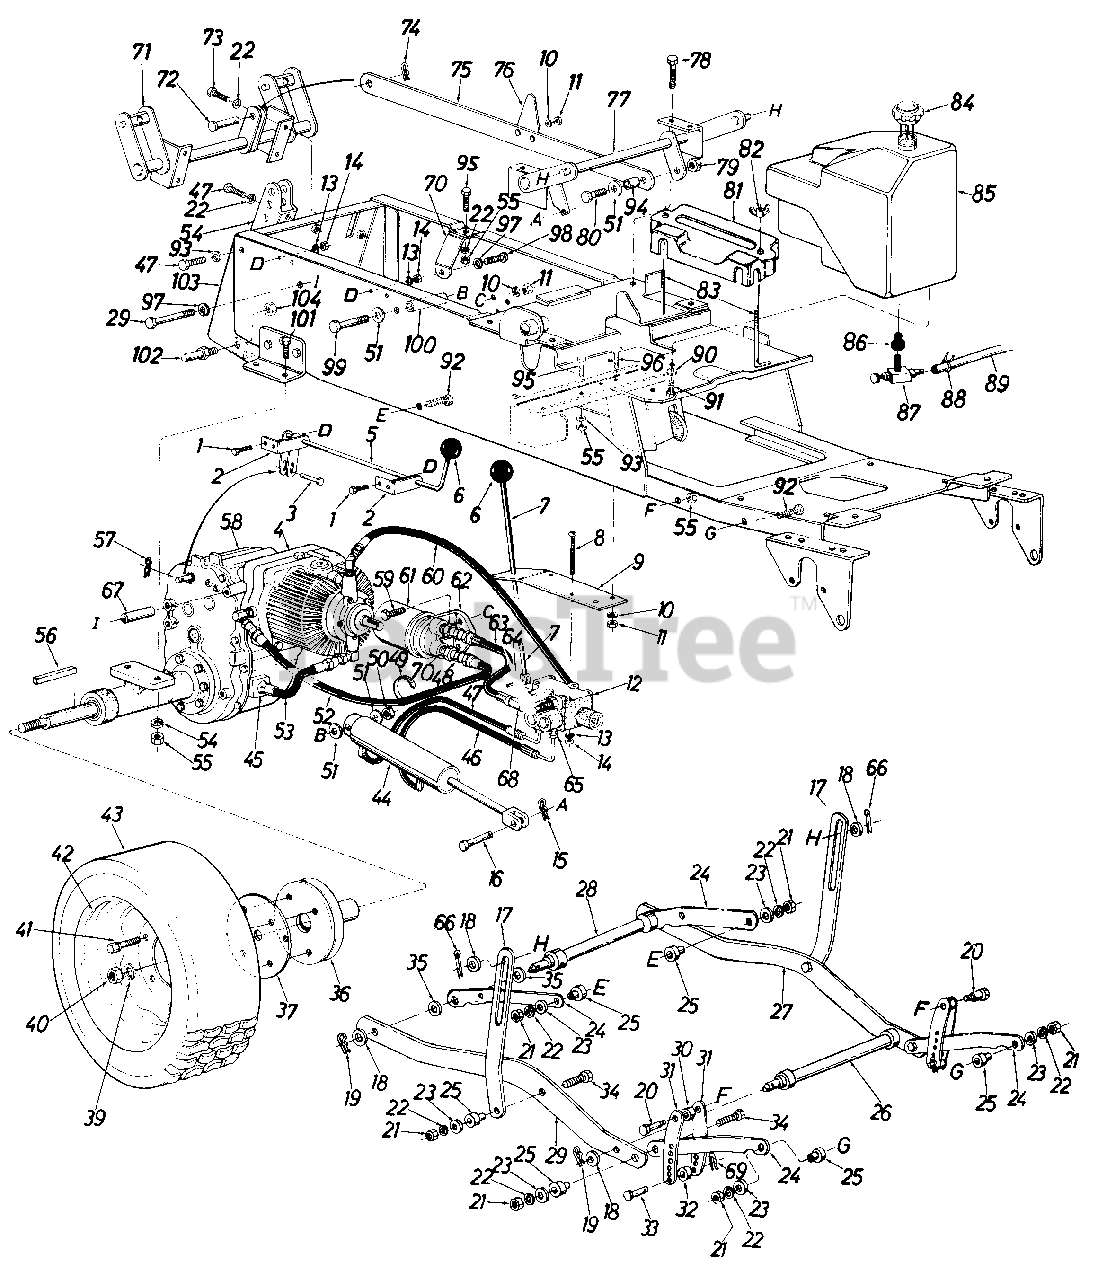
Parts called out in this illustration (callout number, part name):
1	Hex Bolt 1/4-20 x .75" Lg.*
4	Hydrostatic Pump Comp.
5	Hi-Lo Control Handle Ass'y.
6	Ball Knob
7	Cylinder Control Handle Ass'y.
8	Truss Mach. Scr. 1/4-20 x 3.00" Lg.*
11	Hex Nut 5/16-18 Thd.*
12	Valve Ass'y. Comp.
13	L-Wash. 1/4" I.D.*
14	Hex Nut 1/4-20 Thd.*
15	Hairpin Cotter 1/2" Dia.
16	Clevis Pin 1/2" Dia.
19	Hairpin Cotter
20	Shld. Bolt .498 Dia. x .66
21	Hex Nut 3/8-24 Thd.*
22	L-Wash. 3/8" I.D. H.D.
23	Fl-Wash. .38 I.D. x 1.00"
26	Cross Shaft Ass'y. Front
29	Hex Bclt 1/2-13 x 2.75"*
30	Collar .50" I.D. x 1.0"
33	Clevis Pin 3/8" Dia.
34	Hex Bolt 3/8-24 x 1.50" Lg. Grade 5
35	Fl-Wash. .62" I.D. x 1.25"
39	L-Wash. 3/4" I.D.
40	Hex Ins. L-Nut 3/4-16 Thd.
41	Wheel Lug Bolt
44	Hydraulic Cylinder
45	7/8-14 UNF-2A Thd. 5/8 Tube Fitting
46	Valve to Cylinder Hose-20"
47	Hex Bolt 3/8-16 x .75" Lg.- Grade 5
48	Bushing Reducer 1/2-14 NPTF to 3/8-18 NPTF
49	Cable Tie
50	Hex Jam Nut 1/2-20 Thd.
51	Fl-Wash. .50" I.D. x 1.25
52	Filter Return Hose 24" Lg.
53	Pump Tube Ass'y.
55	Hex Nut 3/8-16 Thd.
56	Sq. Key 1/4" x 1/4 x 2"
57	Hairpin Cotter 1/4'1 Dia.
58	Peerless Transaxle
59	Hex Bolt 5/16-18 x 1.25"
60	Pump to Valve Hose
61	Fram Filter Ass'y. PH-16
62	Filter Base
63	Valve to Filter Hose-8.38"
64	Spring Pin Spiral 1/8" Dia.
65	Flare Adapter
66	Cotter Pin 1/8" Dia. x 1.0"
67	Spacer
68	Adapter 9/16-18 to 9/16-18
69	Hairpin Cotter
70	Transmission Brace
73	Hex Scr. 3/8-16 x 1.00" Lg. Grade 5
74	Cotter Pin 1/8" Dia. x 1.25"
79	Hex Cent. L-Nut 1/2-20 Thd.
80	Hex Scr. 1/2-20 x 1.25" Lg.
81	Battery Cover
82	Wing Nut 1/4-20 Thd.
83	Battery Hold Down Rods
84	Gas Tank Cap
85	Gas Tank Ass'y.
86	Bushing
87	Fuel Shut-Off Valve with Screen
88	Gas Line Clamp 7/16"
89	Gas Line 30" Lg.
90	Bell-Wash.
91	Hex Scr. 1/4-20 x .38" Lg.
92	Hex Scr. 3/8-24 x 1.50" Lg.
93	L-Wash. 3/8" Scr.
94	Push Bar Sleeve
95	Hex Scr. 3/8-16 x 1.00 Lg. Grade 5
96	Hex Scr. 5/16-18 x .75" Lg.
97	L-Wash. 1/2" Scr.
98	Hex Scr. 1/2-13 x 1.25" Lg.
99	Hex Scr. 1/2-20 x 3-1/2" Lg. Grade 5
100	Spacer for Cylinder
101	Hex Scr. 3/8-16 x 1.75" Lg.
102	Link Clevis Pin
